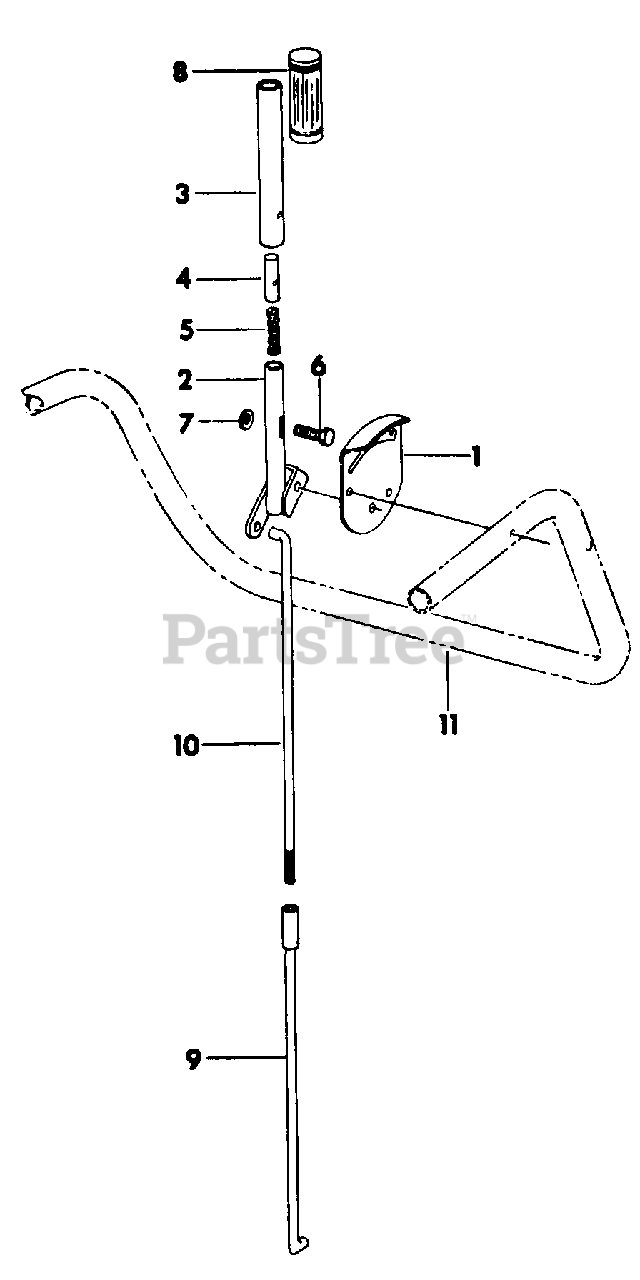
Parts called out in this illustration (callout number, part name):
1	BRACKET, CONTROL SUPPORT
3	HANDLE, SHIFT LEVER
5	SPRING
6	SCREW, 1/4-20 X 1-1/2 HEX-HD CAP
7	WASHER
8	GRIP, HANDLE
9	ROD, CONTROL ADJUSTING LOWER
10	ROD, CONTROL ADJUSTING UPPER
11	BAR, HANDLE
